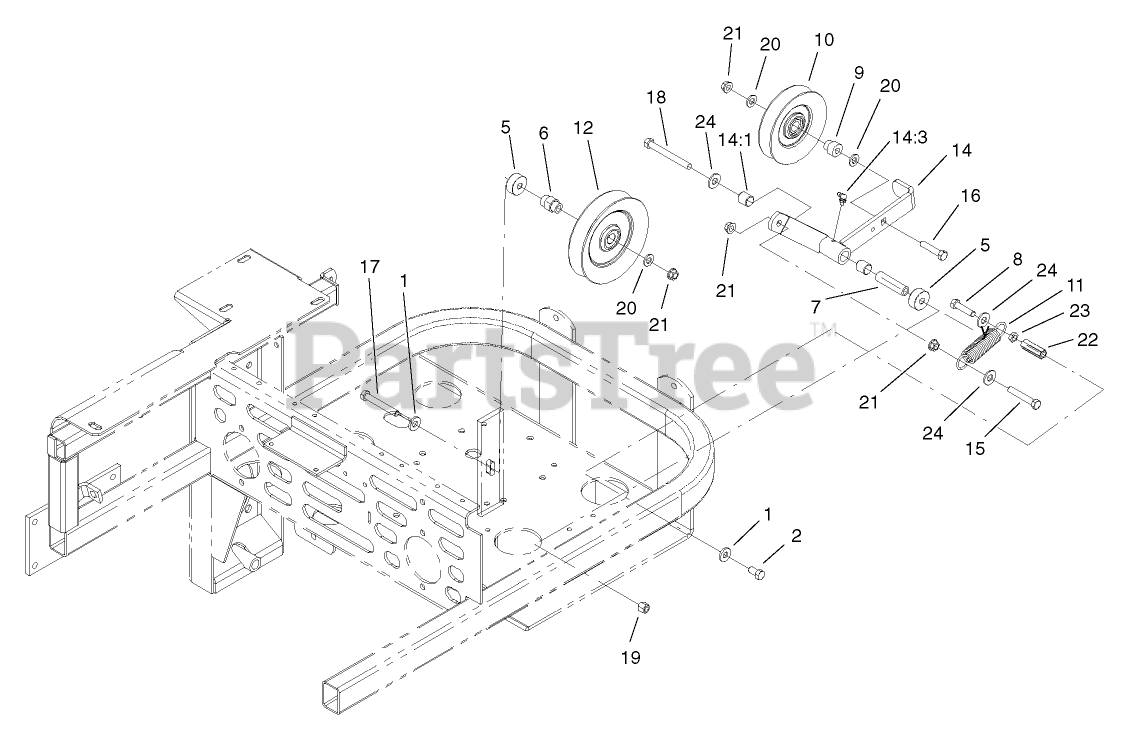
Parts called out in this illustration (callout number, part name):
1	WASHER-BELLEVILLE
2	SCREW-HH
5	Spacer-Idler
6	Spacer (only on: 74236)
6	Bushing-Idler (only on: 74213)
7	BUSHING-PIVOT, IDLER
8	SCREW-HH
9	Bushing-Idler (only on: 74236)
9	Bushing-Idler (only on: 74213)
10	Idler
11	SPRING-EXTENSION
12	PULLEY-IDLER
14	IDLER ARM ASM
14:1	SLEEVE-BEARING
14:3	FITTING-GREASE, 90 DEG
15	SCREW-HH
16	SCREW-HH
17	SCREW-HH
18	SCREW-HH
19	NUT-LOCK, NI
20	WASHER-FLAT
21	NUT-HHF, WHIZ
22	Nut-Coupling
23	NUT-JAM
24	WASHER-FLAT
